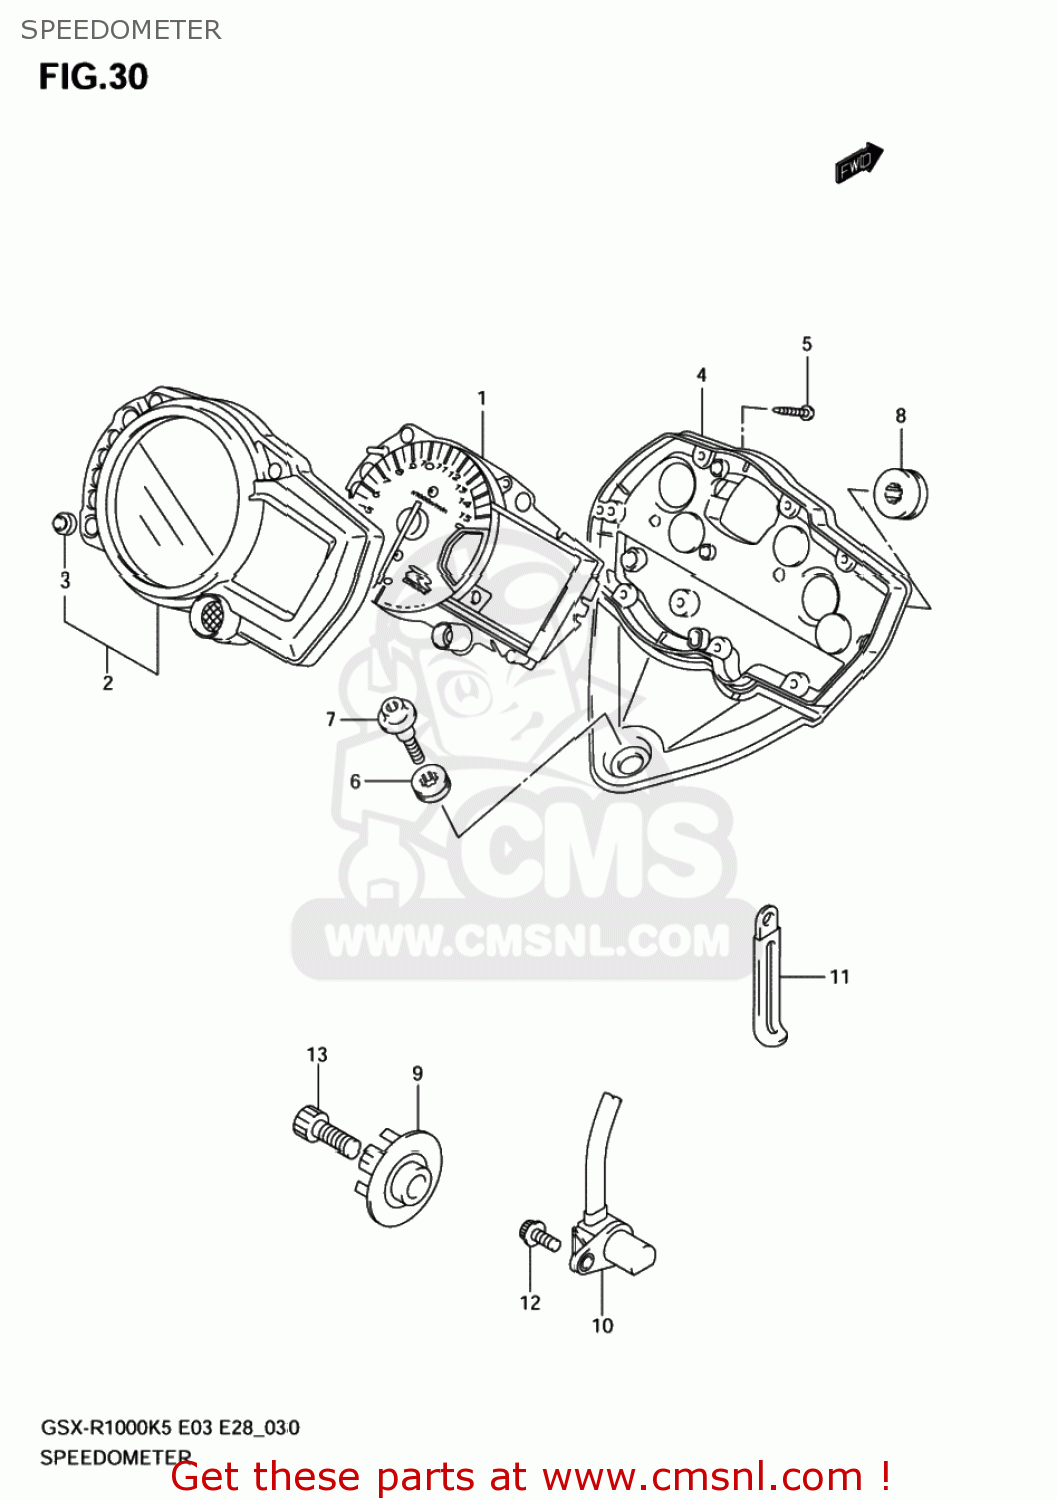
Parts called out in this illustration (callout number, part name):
1	SPEED & TACHOMETER ASSY
2	UPR CASE
3	RUBBER,SWITCH
4	LWR CASE
5	SCREW(3X16)
6	CUSHION,METER
7	SCREW,SPEEDOMETER
8	CUSHION
9	ROTOR,SPEED
10	SENSOR,SPEED
11	CLAMP(L:45)
12	BOLT
13	BOLT
